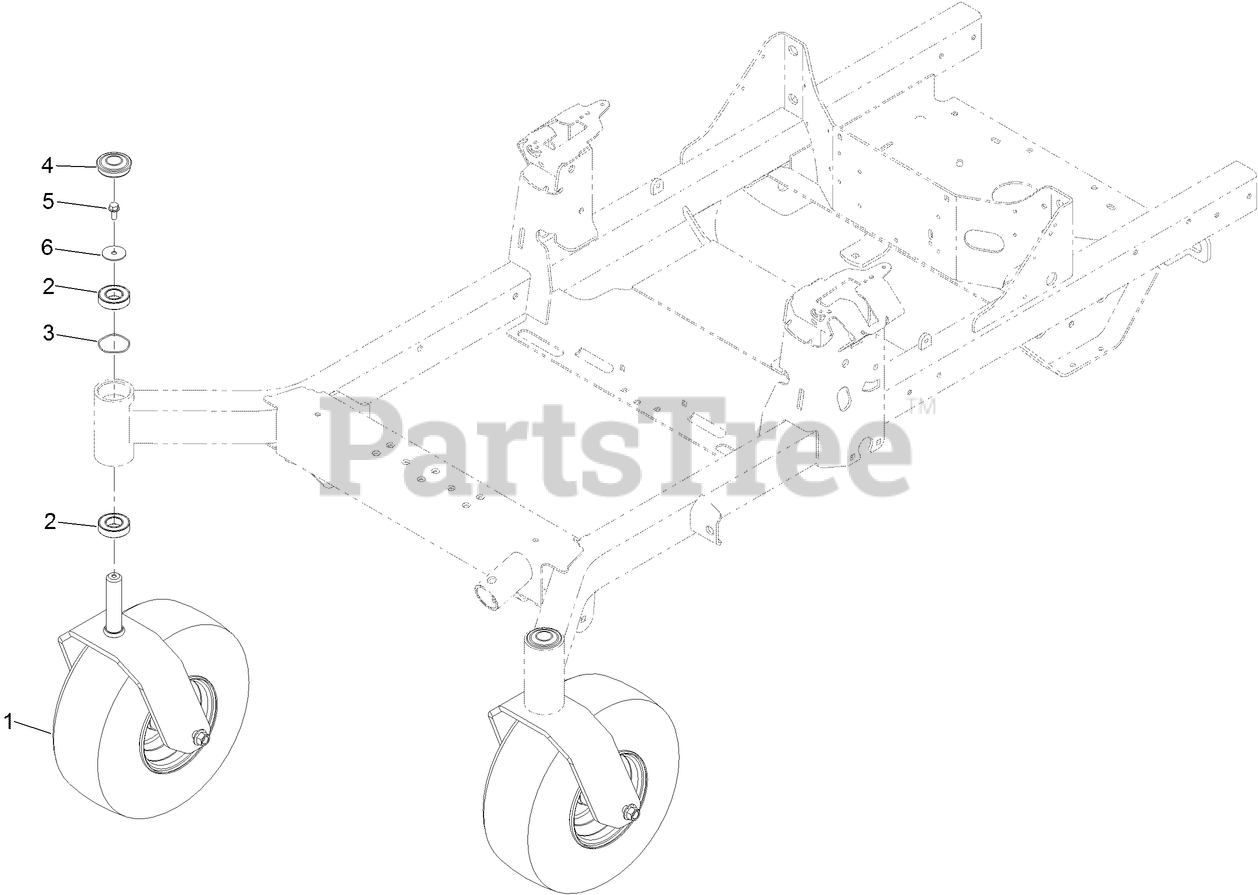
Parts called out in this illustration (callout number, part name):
1	ASM-FRONT CASTOR W/FORK
2	BEARING-BALL
3	SPRING
4	CAP-GREASE
5	SCREW-HHF
6	WASHER-FLAT
